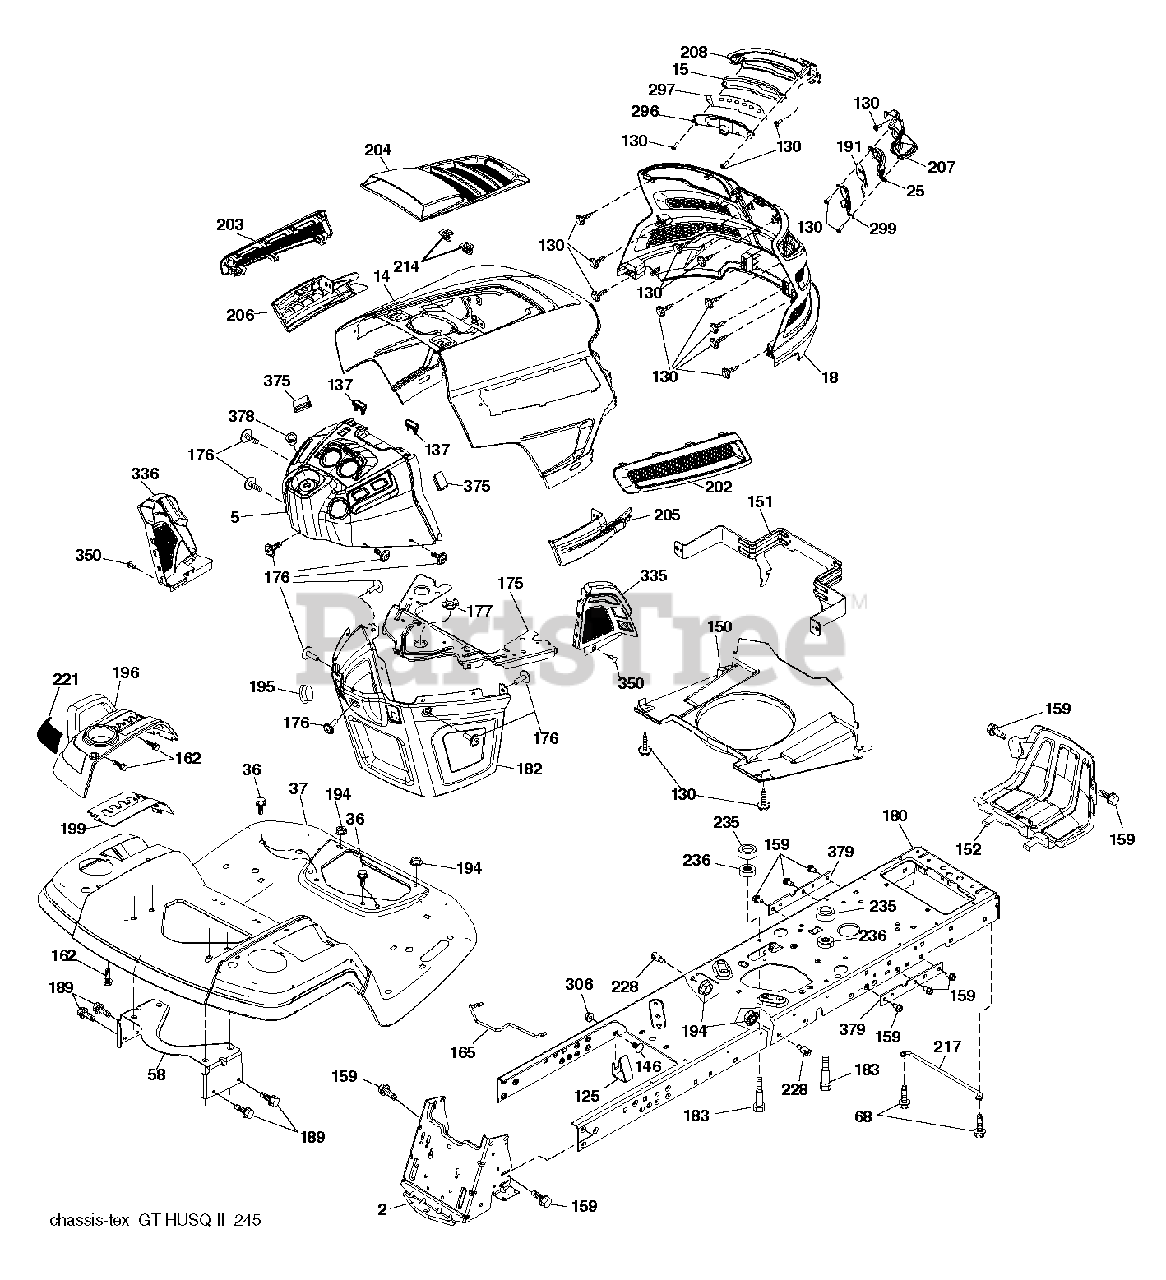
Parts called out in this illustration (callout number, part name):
2	DRAWBAR.STGT
3	APPLIQUE.SUBASM.GT.HUSQ.II
5	DASH.UPR.GT2.DUAL.RD.PT
14	HOOD.ASM.HUSQVARNA.GT.TEX.ORAN
15	LED LIGHT.LH
18	GRILLE SUBASM.GT.II.LOW.HDLGHT
25	LENS.RH
36	SCREW 5/16"
37	FENDER HUSQVARNA GT MS668 - HU
58	BRKT.SUPPORT.FNDR/TANK
68	SCR 5/16-18 X 1/2 SELFTAP ZN
125	CLIP.FUEL.LINE
130	SCREW.#10 X 0.750.BOS
137	BUMPER DASH
146	BOLT.RDHD.SHT.SQNK.3/8-16X5/8
150	AIR.DUCT.GTV.BLACK
151	BRACKET.PIVOT.HOOD.GT.HUSQ.II
152	SHIELD.BROWNING.PNT.GT.V2
159	SCREW, 3/8-16X3/4
162	SCREW.HI-LO.CONSOLE
165	SUPPORT.TANK.REAR.B/TE
175	Crossmember Plate
176	SCREW.#10-24X5/8.RN.QU
177	BUSHING STEERING
180	CHASSIS.LT/GT.BOLTED
182	DASH.LOWER.COMMON.12V.ADAPTOR
183	BOLT.5/16-18X1-1/4 FULL THD
189	SCREW
191	INSERT INFLECT.RH
194	NUT LOCK HEX FLANGE 5/16-18
195	PLUG.HOLE.DASH.LOWER.12V.BLK
196	CONSOLE.ASM.DECKLIFT.HUSQGT.DL
199	PLATE.DECK.LIFT.HUSQVARNA.GT
202	VENT.SIDE.RH.GT.HUSQ.II.
203	VENT.SIDE.LH.GT.HUSQ.II.498
204	VENT.TOP.HUSQ.GT2
205	SIDE.TRIM.RH.GT.HUSQ.II
206	SIDE.TRIM.LH.GT.HUSQ.II.GRAY
207	BEZEL GT2 LED RH W/ LOWER.ATT
208	BEZEL GT2 LED LH W/ LOWER ATT
214	CLIP.RETAINER.TINNER.
217	ROD.PIVOT.HOOD
221	REFLECTOR.LH.TEX GT HU
228	STUD.FASTNER.W/ANTI-ROTATE
235	SPACER FENDER
236	NUT.CENTERLOCK.5/16-
296	LED LIGHT.LH
297	INSERT REFECT LH
299	LED LIGHT.RH
306	NUT LOCK FLG 3/8-16 UNC
335	COVER.LOWER.DASH.RH.BLACK
336	COVER-LH.LOWER.DASH.GT2.BLACK
350	KIT GUARD BRUSH
375	BUMPER CLIP-ON. DASH 1"
378	BUSHING FLANGE; PLASTIC
379	CHASSIS.PLATE.REINFORCEMNT.431
